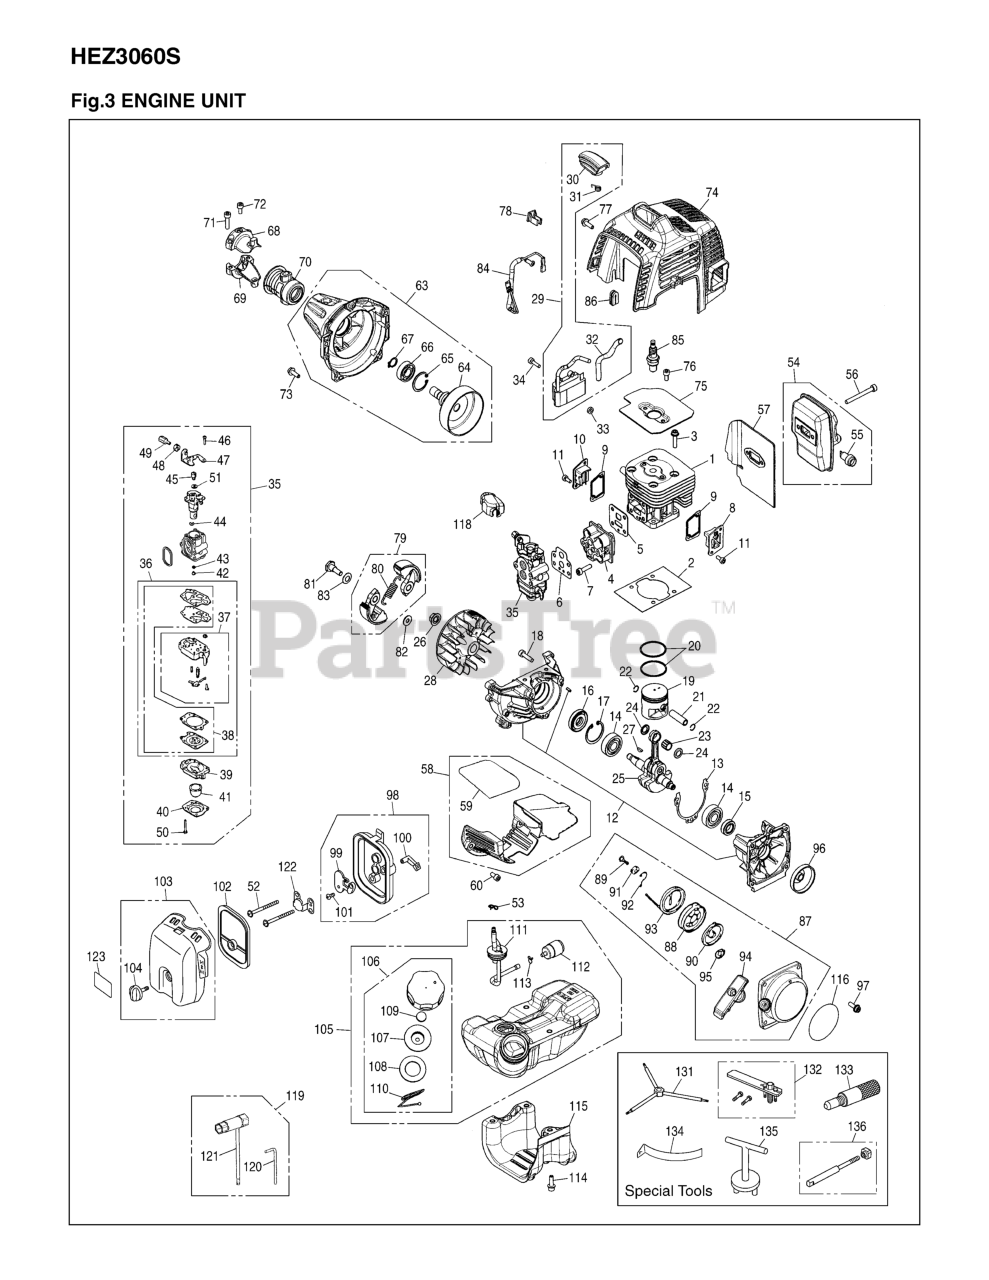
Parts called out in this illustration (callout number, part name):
1	CYLINDER
2	GASEKT, BASE
3	BOLT
4	INSULATOR
5	GASKET, INSULATO
6	GASKET, CARB (RP
7	BOLT, TORX
8	COVER, TRS
9	GASKET, TR
10	COVER,TRF (RPLS
11	BOLT
12	CRANKCASE-C
13	GASKET, CASE
14	BEARING
15	SEAL
16	SEAL, OIL (RPLS
18	BOLT (RPLS 28501
20	RING
21	PIN
22	RING, SNAP
23	BEARING
24	WASHER (RPLS 331
25	CRANKSHAFT-C
26	NUT (RPLS 1140-4
27	KEY
29	COIL-A
30	CAP(RPLS 4810721
31	SPRING
32	TUBE (RPLS 26167
34	BOLT TORX
35	CARBURETOR ASSY
36	REBUILD KIT
37	BODY, PUMP
38	GASKET KIT
39	BODY, PURGE
40	COVER, PUMP
41	PUMP, PRIMING
42	JET (RPLS 481081
43	RING, O
49	SCREW
50	SCREW
51	WASHER
52	BOLT TORX
53	CLIP
54	MUFFLER ASSY
55	ARRESTER
56	BOLT
57	GASKET
60	BOLT
63	HOUSING ASSY
64	DRUM (RPLS 48103
68	BRACKET (A) (RPL
69	BRACKET (B)
70	CUSHION (RPLS T1
71	BOLT (RPLS 28501
72	BOLT
73	BOLT
74	COVER, ENGINE
75	PLATE
76	BOLT
77	BOLT, TORX
79	SHOE
80	SPRING
81	BOLT
82	WASHER
83	WASHER (RPLS 114
84	CORD COMP.
85	SPARKPLUG
86	GROMMET
87	RECOIL-A
88	REEL
89	SCREW
90	SPRING, SPIRAL
91	COLLAR
92	ARM
93	ROPE (RPLS 45007
94	KNOB (RPLS 3330-
95	PLATE, STOPPER
96	PULLEY
97	BOLT, TORX
98	CLEANER BODY ASS
99	PLATE, CHOKE
101	SCREW
102	ELEMENT
103	COVER ASSY
104	CLEANER KNOB
105	TANK(EVAPO)
106	CAP ASSY
107	HOLDER (RPLS 450
108	PACKING
109	FILTER
110	STOPPER
111	PIPE-C
112	FILTER
113	CLIP (RPLS 28413
114	BOLT
115	GUARD, TANK
116	LABEL, RECOIL
118	COVER
119	Tool-Set
120	BAR
131	WRENCH (RPLS 267
132	PULLER ASSY(R107
133	STOPPER (TOOL)
134	GAUGE, AIR GAP (
135	PULLER, RECOIL (
